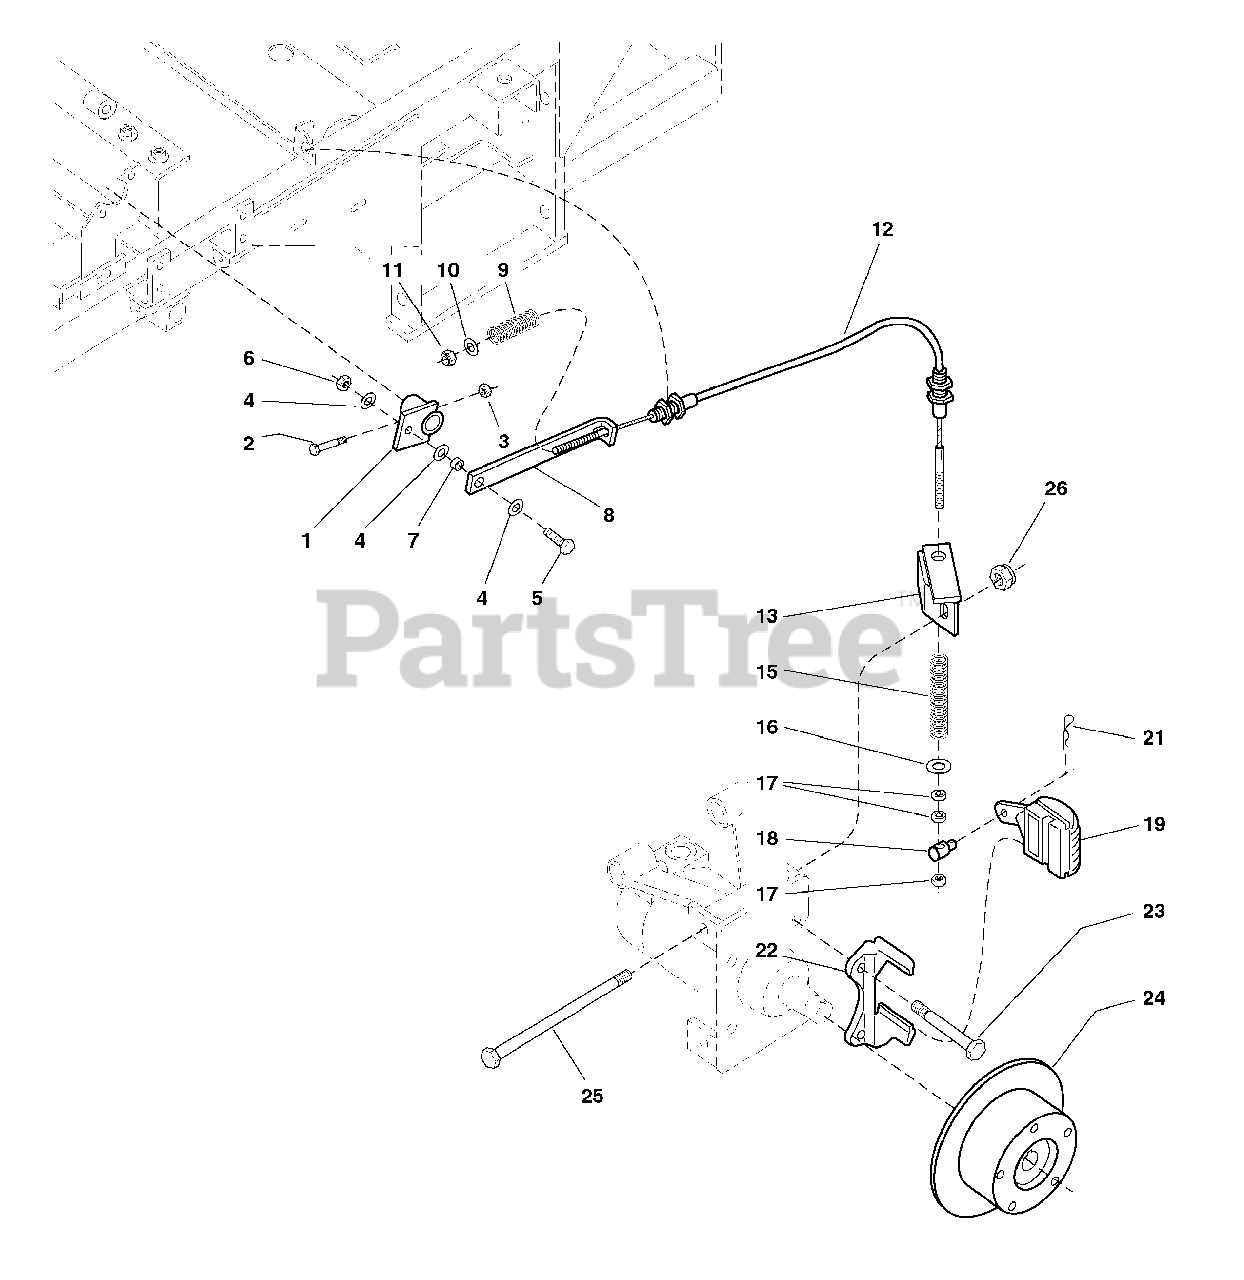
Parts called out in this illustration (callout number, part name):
1	BRAKE LINKAGE PIVOT (LH only)
2	CAPSCREW, Hex Hd, 1/4-20 x 1-3/4
3	NUT, Hex, Nylon Lock, 1/4-20
4	WASHER, 3/8
5	CAPSCREW, Hex Hd, 3/8-16 x 1-1/4
6	NUT, Hex, Nylon Lock, 3/8-16
7	SPACER, Pivot
8	LINK, Brake Lock
9	SPRING, Compression
10	WASHER, 5/16
11	NUT, Hex, Nylon Lock, 5/16-18
12	CABLE, Brake
13	BRACKET, Cable Mount-LH
15	SPRING, Compression
16	WASHER, Fender, 5/16
17	NUT, Hex, 5/16-24
18	ADJUSTER, Brake Linkage
19	BRAKE CALIPER, LH
21	HAIRPIN CLIP
22	MOUNT, Brake Caliper
23	CAPSCREW, Hex Hd, 1/2-20 x 3
24	HUB, 8" Brake Disc
25	CAPSCREW, Hex Hd, 1/2-13 x 7-1/2
26	NUT, Hex, Nylon Lock, 1/2-13
